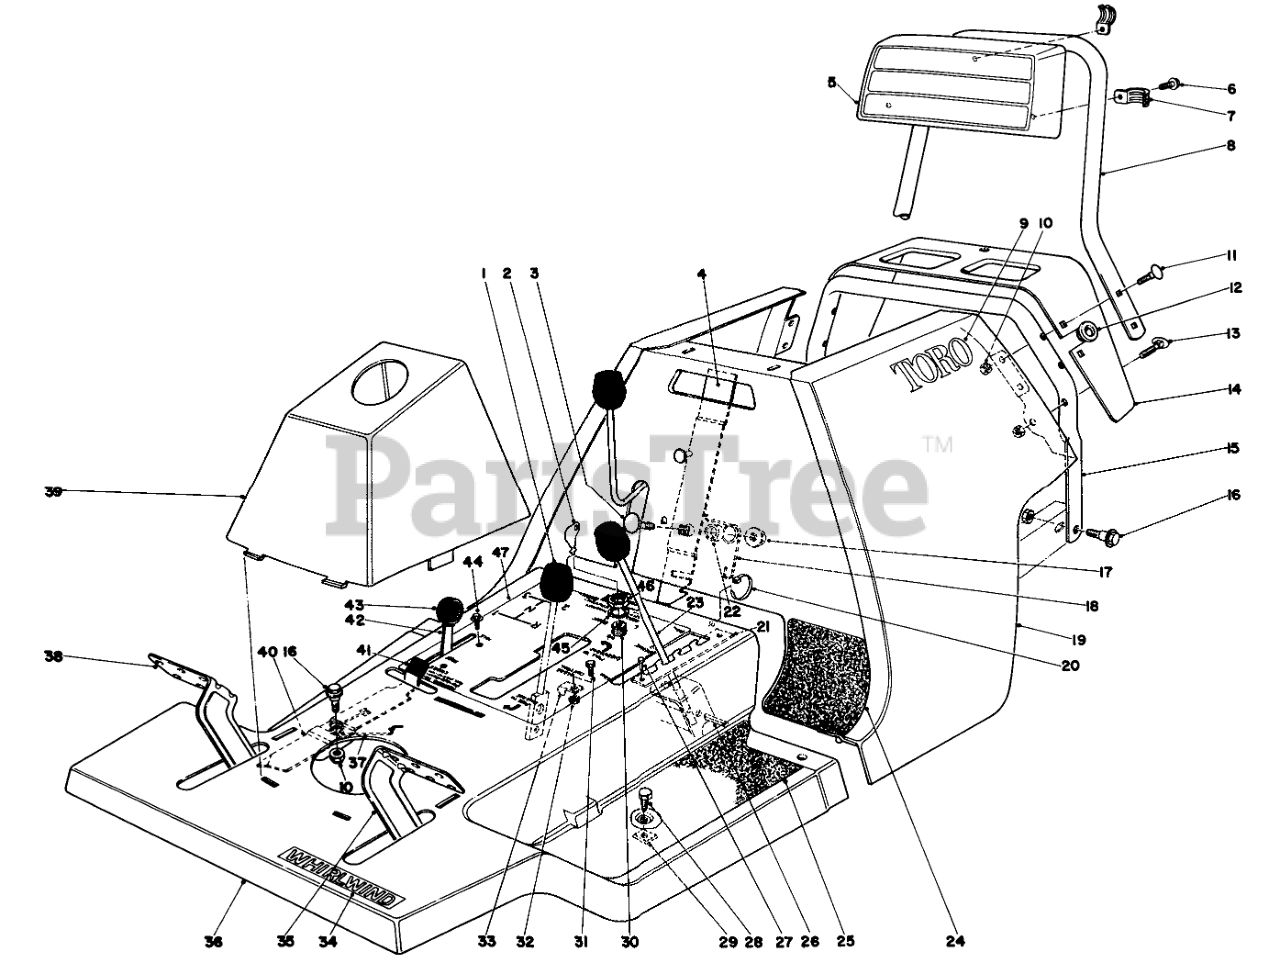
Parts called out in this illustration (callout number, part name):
2	Key
3	BOLT-CARR
4	Handle Latch
5	Backrest
6	SCREW-HHF
7	CLAMP-CONDUIT
8	Handle Upper
9	TORO LOGO DECAL
10	NUT-LOCK, CONE
11	SCREW-CARR
12	Starting Ferrel
13	HANDLE SCREW
14	Extension Rear Body
15	Handle Lower
16	SCREW-SHOULDER
17	NUT-HF
18	Latch Return Spring
19	Rear Body
20	TIE-CABLE
21	Height Adjustment Plate
22	Spacer
23	Height of Cut Lever
24	Heel Pad-LH.
25	Foot Tread LH.
26	PIN-SPECIAL
28	SCREW-HH
29	NUT-TINNERMAN
30	Starter Switch (Incl. Ref. #2, 45 & 46)
32	NUT-KEPS
33	CABLE CLAMP
34	WW DECAL
35	Clutch Pedal
36	Body Front (Incl. Ref. #21, 27 & 47)
37	SPRING-PARKING BRAKE
38	Brake Pedal
39	Tower
40	Parking Brake
41	TIP-PARKING BRAKE
42	Throttle Control (Incl. Ref. #43)
44	8X1/2 SELF TAP SCREW
45	WASHER-TOOTH, INTERNAL
46	NUT-HH
47	Decal-Front Body
